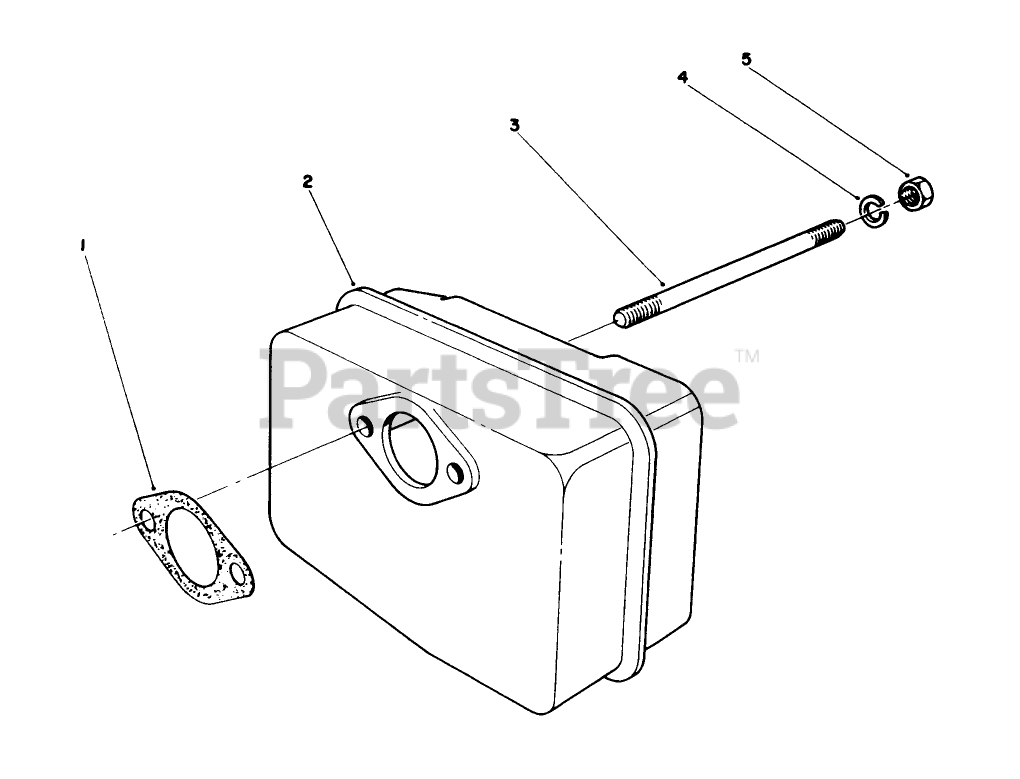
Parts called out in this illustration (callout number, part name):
1	GASKET
2	MUFFLER
4	110 Nut
5	10 Hex Nut
